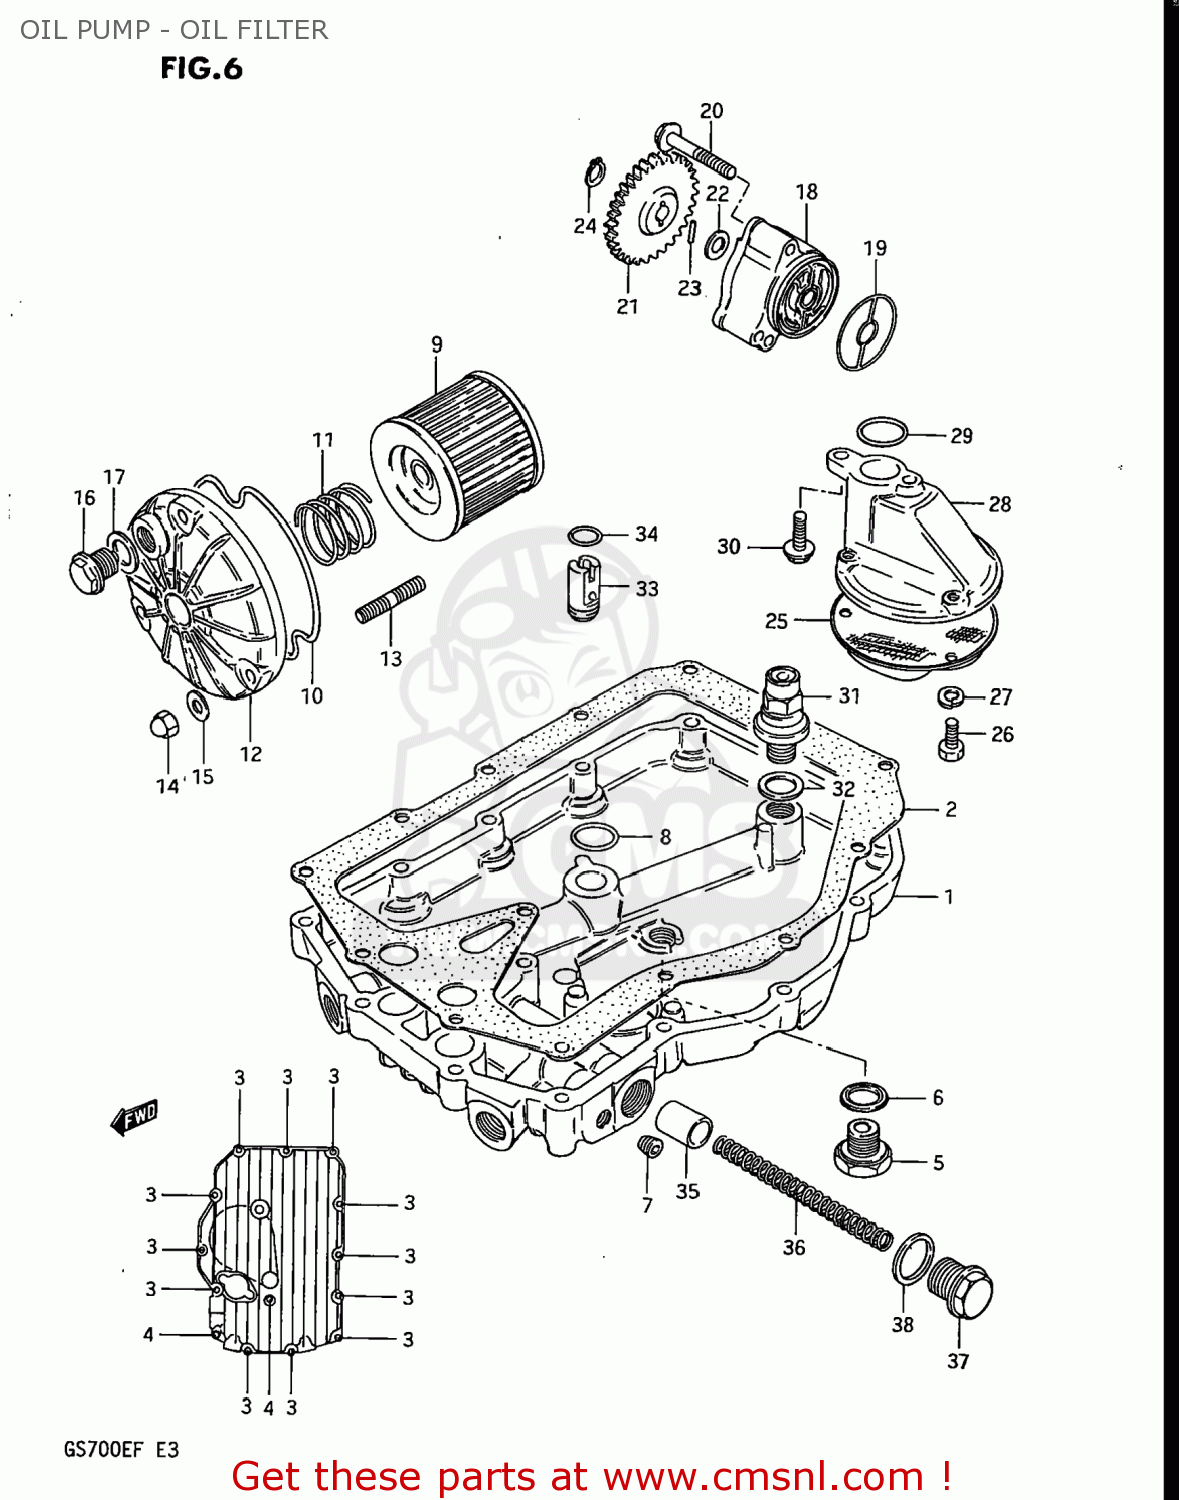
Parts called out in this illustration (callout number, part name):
1	PAN,OIL
2	GASKET,OIL PAN (MCA)
3	BOLT 6X30
4	BOLT
5	PLUG
6	GASKET(14X19.2X2) (NAS)
7	PLUG
8	O RING(D:3.2,ID:15.8)
9	FILTER ASSY,ENGINE OIL
10	O RING,OIL FILTER CHAMBER CAP
11	SPRING
12	CAP,OIL FILTER
13	STUD 6X20
14	NUT 6MM
15	WASHER
16	PLUG(14X12)
17	GASKET(14X19.2X2) (NAS)
18	PUMP ASSEMBLY,OIL
19	O-RING,OIL PUMP
20	BOLT
21	GEAR,OIL PUMP DRIVEN
22	SHIM
23	PIN(4X15.8)
24	CIRCLIP
25	STRAINER,ENGINE OIL
26	BOLT
27	LOCK WASHER
28	PROTECTOR,OIL STRAINER
29	O RING(D:3.2,ID:17.8)
30	BOLT,REAR
31	REGULATOR ASSY,ENGINE OIL
32	WASHER
33	VALVE ASSEMBLY,PISTON OIL
34	O RING(D:1.3,ID:9.8)
35	PLUNGER,OIL CONTROLL
36	SPRING
37	PLUG
38	O RING(D:2.4,ID:16.8)
